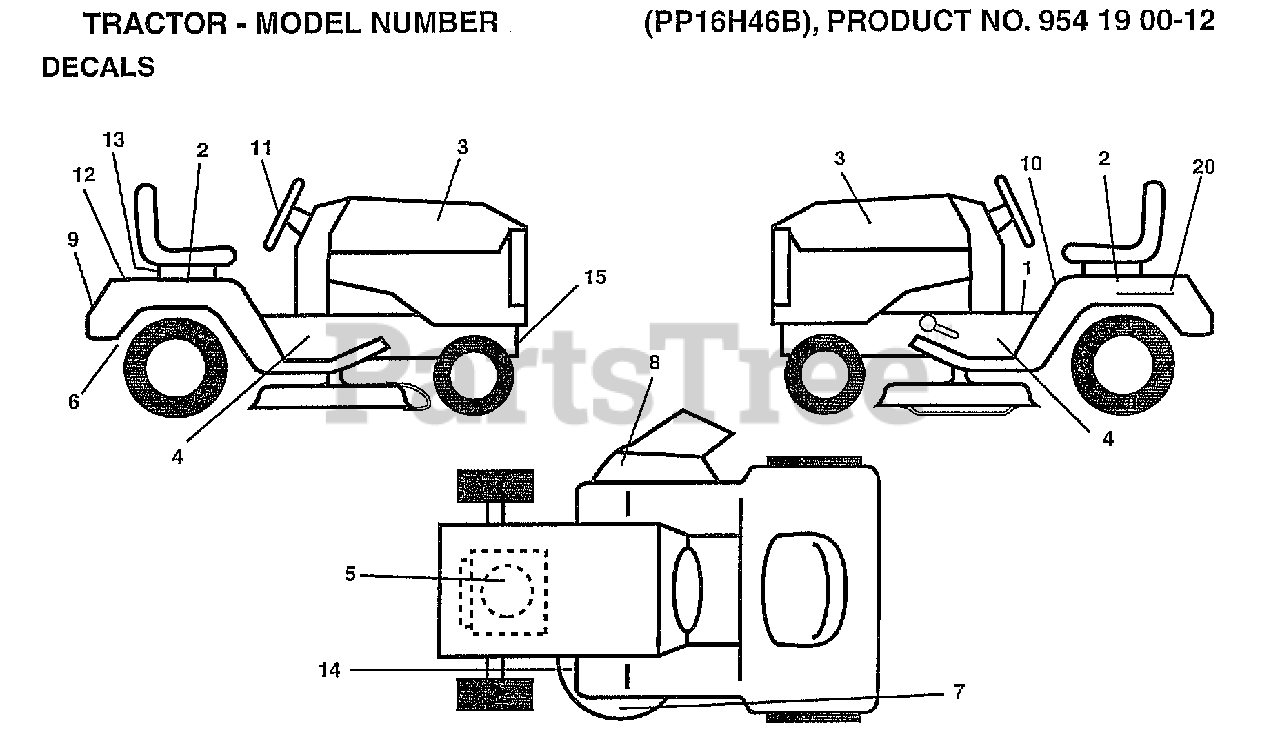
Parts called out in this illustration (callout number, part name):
1	"DECAL FENDER,OPER"
2	DECAL FENDER AUTO
3	DECAL HOOD PREDAT
4	"DECAL CHASSIS 46"""
5	DECAL, ENGINE B&S
6	DECAL DRAWBAR LH
7	"DECAL,ENVIRO DECK"
8	"DECAL, WARNING"
9	DECAL FENDER DOME
10	DECAL.CAUT.ENG/FR
11	DECAL INS STRG WH
12	DECAL FENDER PRED
13	RETAINER-SPRING
14	"DECAL.V.BELT.44"""
15	DECAL CHASSIS PRE
20	DECAL.BATRY.3-3908
